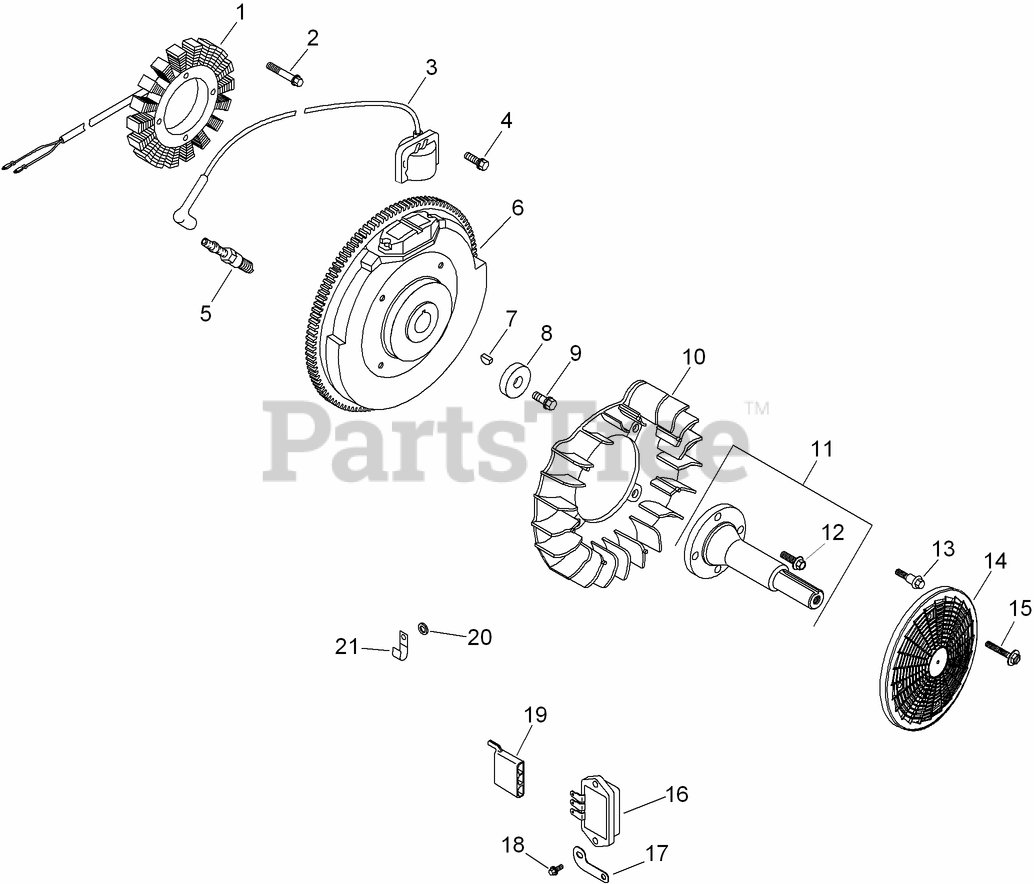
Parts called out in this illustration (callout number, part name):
1	15 AMP STATOR KIT (INCLUDES 25 452 01-S)
2	SCREW-THREAD FORMING (M5X0.8X25)
3	MODULE SPARK ADV (D S A I) ASM
4	SCREW-FLANGE, THREAD FORMING (M5X.8X20)
5	SPARK PLUG (PRO SERIES)
6	FLYWHEEL ASM (L W)
7	KEY (3/16 X 5/8)
8	WASHER-FLAT (13/32)
9	SCREW-FLANGE (M10X1.5X45)
10	Fan
11	Shaft-Drive, Front
12	Screw-HF (M8x1.25x25)
13	BOLT-SHOULDER (M6x1.0x16)
14	Screen-Grass
15	SCREW-FLANGE, SEMS (M4X.7X25)
16	Rectifier-Regulator
17	Bracket-Strap, Ground
18	SCREW-HEX FLANGE, HI-LO
19	CONNECTOR (3 CONTACT)
20	WASHER-FLAT (1/4)
21	CLIP-CABLE
